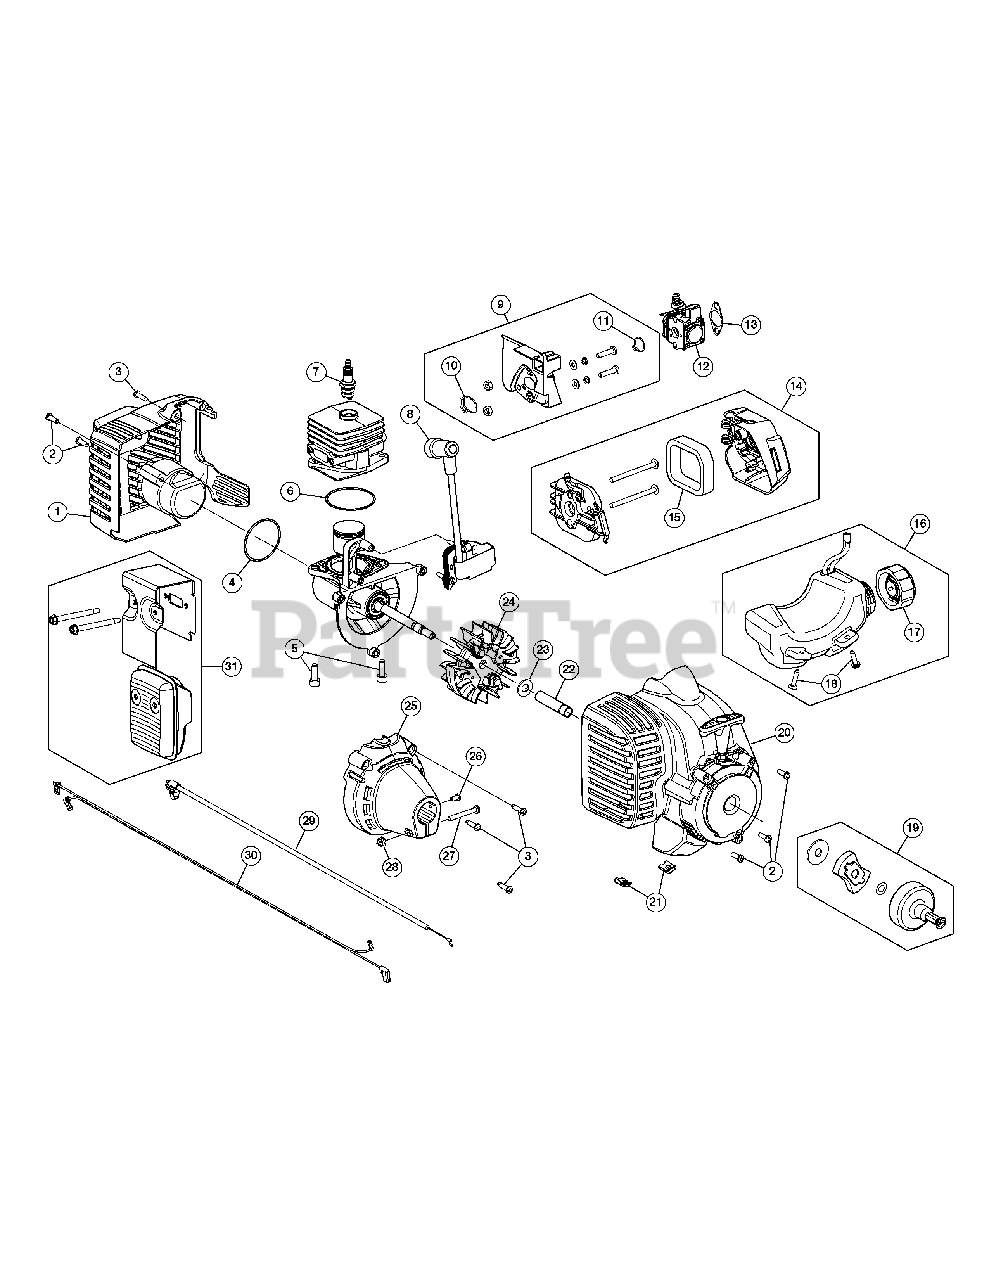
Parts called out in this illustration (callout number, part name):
1	Rear Cover Assembly (Incl. 2 & 3)
2	Housing Screw
3	Cover Screw
4	O-Ring
5	Crankcase Bolt
6	Crankcase O-Ring
7	Spark Plug
8	Module Assembly
9	Insulator Assembly (Incl. 10 & 11)
10	Insulator O-Ring
11	Carburetor O-Ring
12	Carburetor
13	Air Cleaner Gasket
14	Aircleaner Cover Assembly (Incl. 15)
15	Aircleaner Filter
16	Fuel Tank Assembly (Incl. 17 & 18)
17	Fuel Tank Cap
18	Fuel Tank Screw
19	Starter Clutch Assembly
20	Starter Housing (Incl. 2 & 21)
21	U-shaped Nut
22	Spacer
23	Washer
24	Flywheel Assembly
25	Clutch Cover (Incl. 3)
26	Anti-rotation Screw
27	Clamp Screw
28	Clamp Nut
29	Throttle Cable
30	Lead Wires
31	Muffler Assembly
